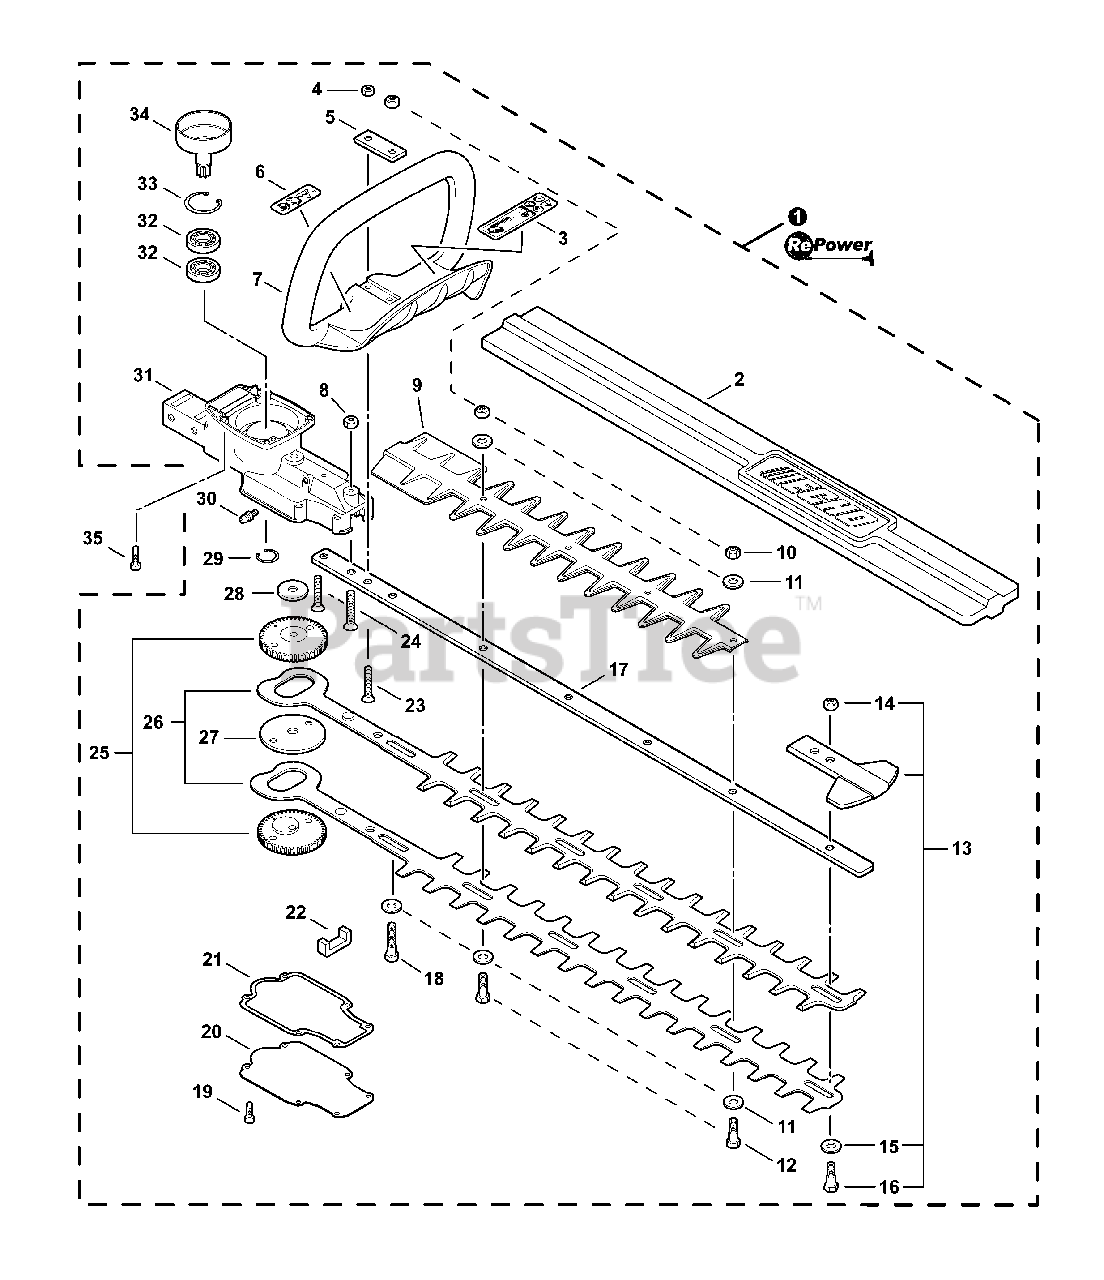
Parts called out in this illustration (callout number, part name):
1	HEAD ASSY, CUTTING
2	SCABBARD
3	LABEL, CAUTION - ISO
4	NUT, FLANGE M5
5	PLATE, EYE
6	LABEL, CAUTION
7	HANDLE, FRONT
8	NUT, HEX M6
9	STIFFENER, BLADE
11	WASHER 6.5×15.5×0.6
12	BOLT 6×18
13	TIP GUARD KIT
15	WASHER 6.5×15.5×0.6
16	BOLT 6×18
17	SUPPORT, BLADE
18	BOLT M6×35
19	BOLT, TORX 4×12
20	COVER, GEAR CASE
21	GASKET, GEAR CASE
23	SCREW 5×30
24	SCREW 6×30
25	GEAR, SPUR
26	CUTTER
27	WASHER 6.7×54×0.38
28	WASHER 6.5×30×0.2
29	RING, SNAP 14
30	FITTING, GREASE
31	CASE, GEAR
32	BEARING, BALL 6202
33	RING, SNAP 35
34	DRUM, CLUTCH
35	BOLT, TORX 4×16
